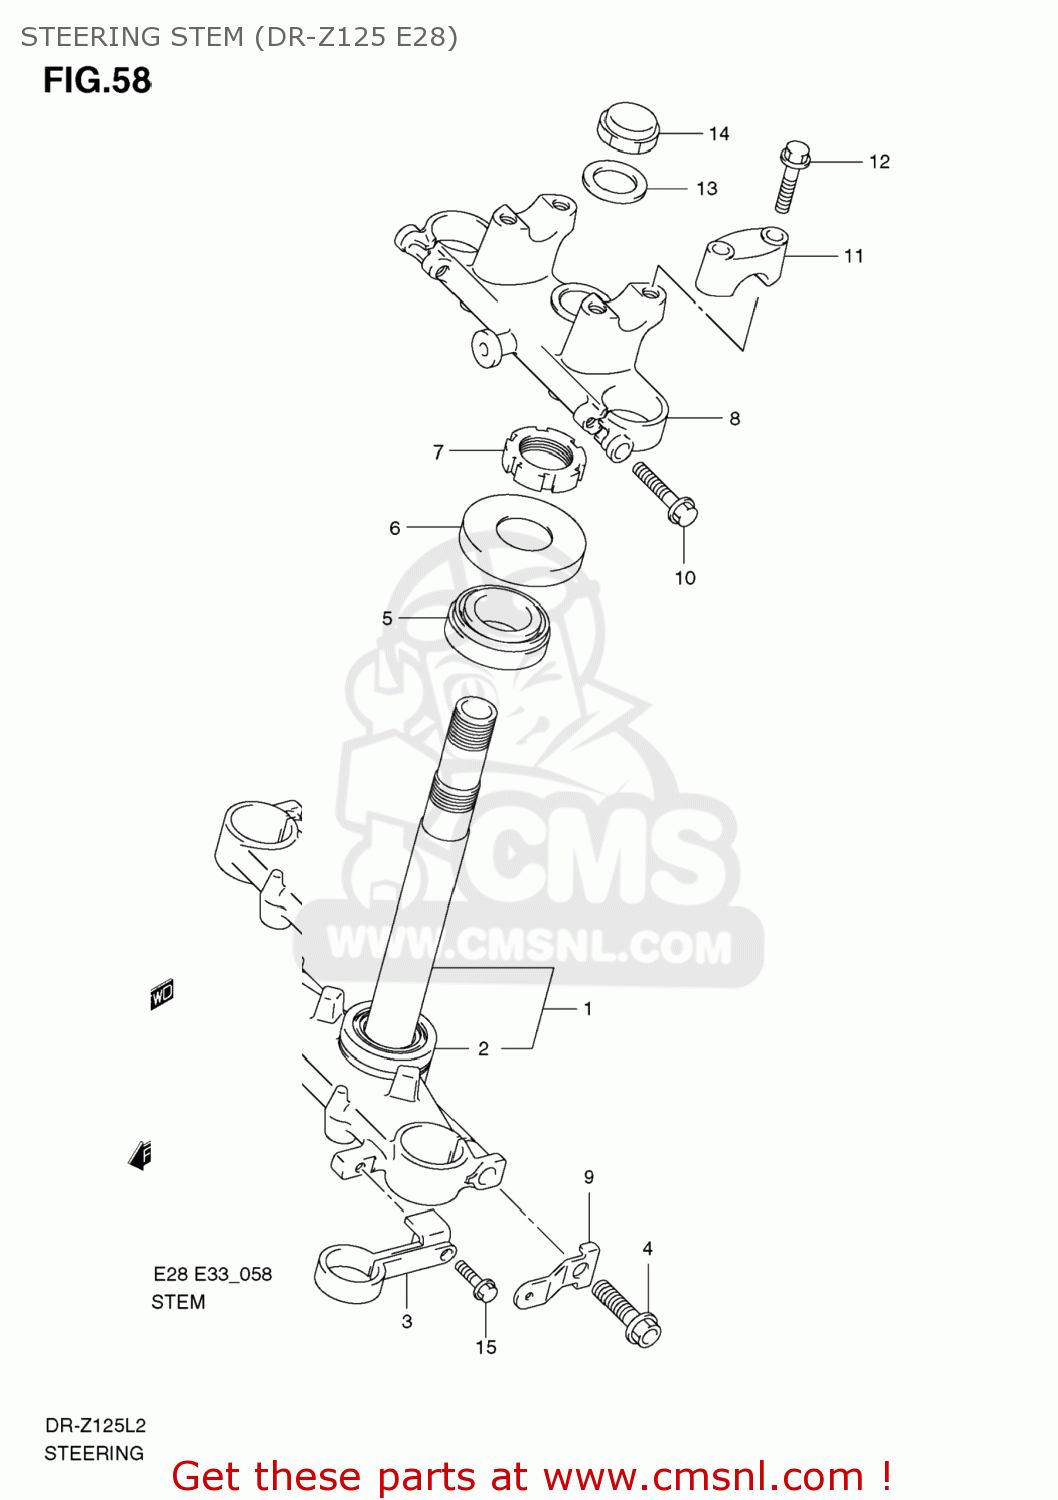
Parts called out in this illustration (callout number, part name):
1	STEM,STEERING
2	BEARING(26X47X15)
3	GUIDE,FR BRAKE HOSE
4	BOLT
5	BEARING(25X47X15)
6	SEAL,STEERING UPR DUST
7	NUT,STEERING
8	BRACKET,UPR
9	BRACKET,FR SIDE RR
10	BOLT
11	HOLDER,HANDLE
12	BOLT
13	WASHER
14	NUT
15	BOLT
